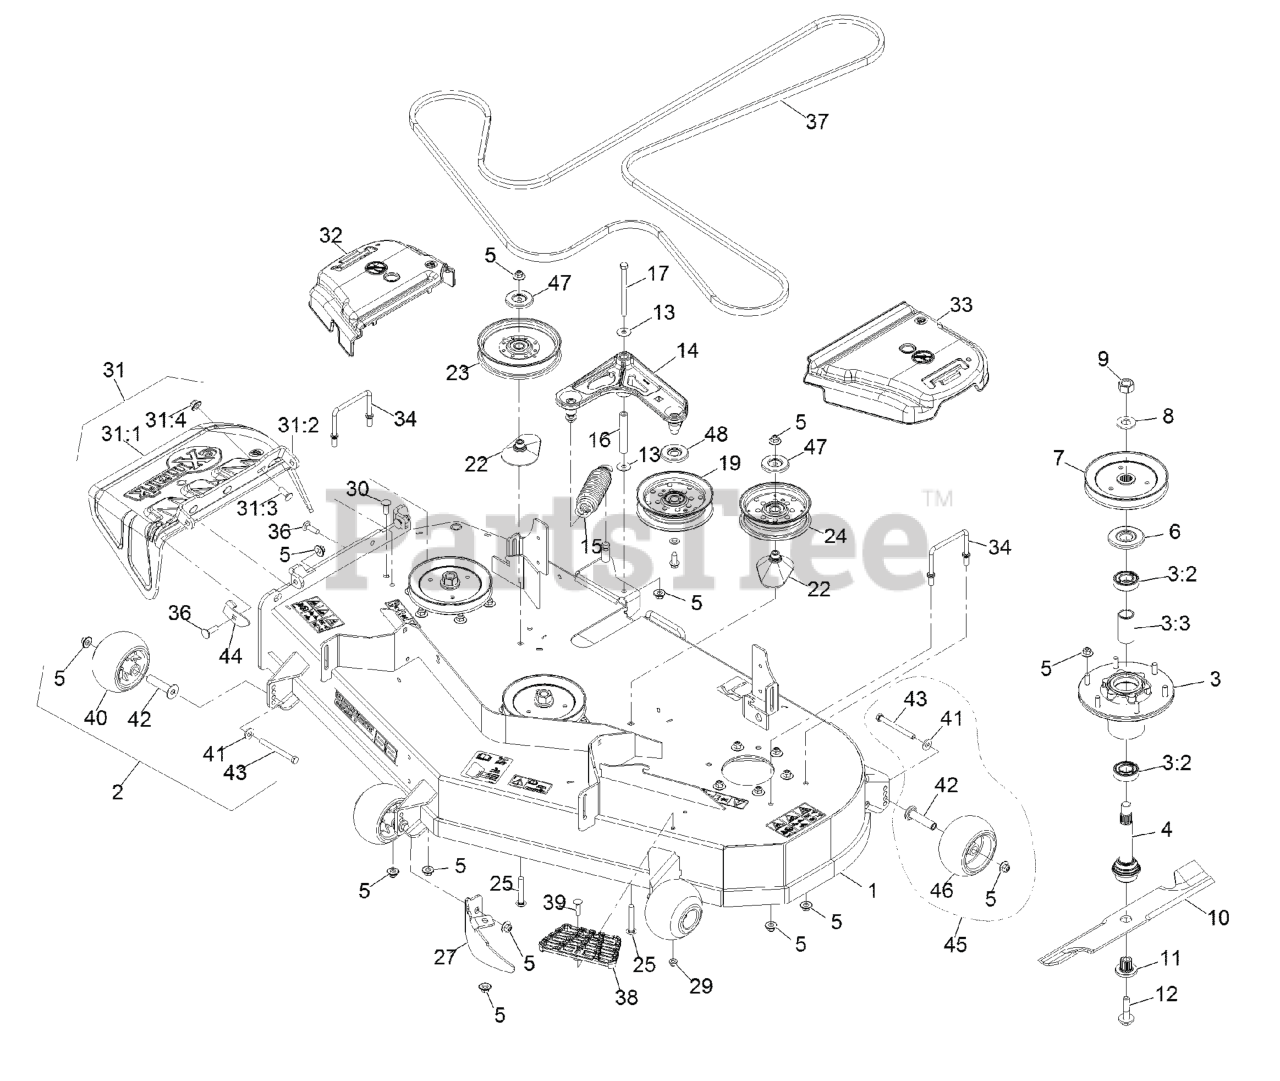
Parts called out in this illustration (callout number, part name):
1	ASM-DECK W/DECALS 524
2	KIT, ANTI-SCALP ROLLER
3	ASM-CUTTER HSG WITH BEARINGS
3:2	BEARING-BALL
3:3	SPACER-BEARING
4	ASM-SPINDLE AND SEAL
5	Nut-Nyloc 3/8-16 Flg
6	GUARD,BEARING TOP .989
7	SHEAVE,BLADE DRIVE 6.50
9	NUT-HEX
11	BUSHING,SPLINED
12	SCREW,SEMS 1/2-20 X 2.19
14	IDLER ARM ASM
15	SPRING-EXTENSION
16	BUSHING
17	SCREW-HH
19	IDLER-PULLEY, FLAT
22	SPACER-PULLEY
23	IDLER-PULLEY, FLAT 6.00X1
24	IDLER-PULLEY, FLAT 5.00X1
25	SCREW-CARR
27	BAFFLE-DOGLEG, LZ-VT52
29	NUT-HF, NI
30	SCREW-CARR
31	ASM,DISCHARGE CHUTE
31:1	CHUTE,DISCHARGE
31:2	BRACKET,DISCHARGE CHUTE
31:3	SCREW-CARR
31:4	Nut-Nyloc 3/8-16 Flg
32	COVER-BELT, RH
33	COVER-BELT, LH
34	WIREFORM-COVER
36	BOLT-CARR
37	BELT-V
38	STEP-DECK
39	Bolt-Carriage 5/16-18 X 1 1/4
40	ROLLER-SCALP, ANTI
41	WASHER-BELLEVILLE
42	AXLE, ROLLER
43	SCREW-HH 3/8-16 X 3 3/4 GR 8
44	STOP-DISCHARGE CHUTE
45	KIT-ANTISCALP ROLLER
46	ROLLER-SCALP, ANTI
47	SHIELD-DUST
48	SHIELD-GUARD, DUST
